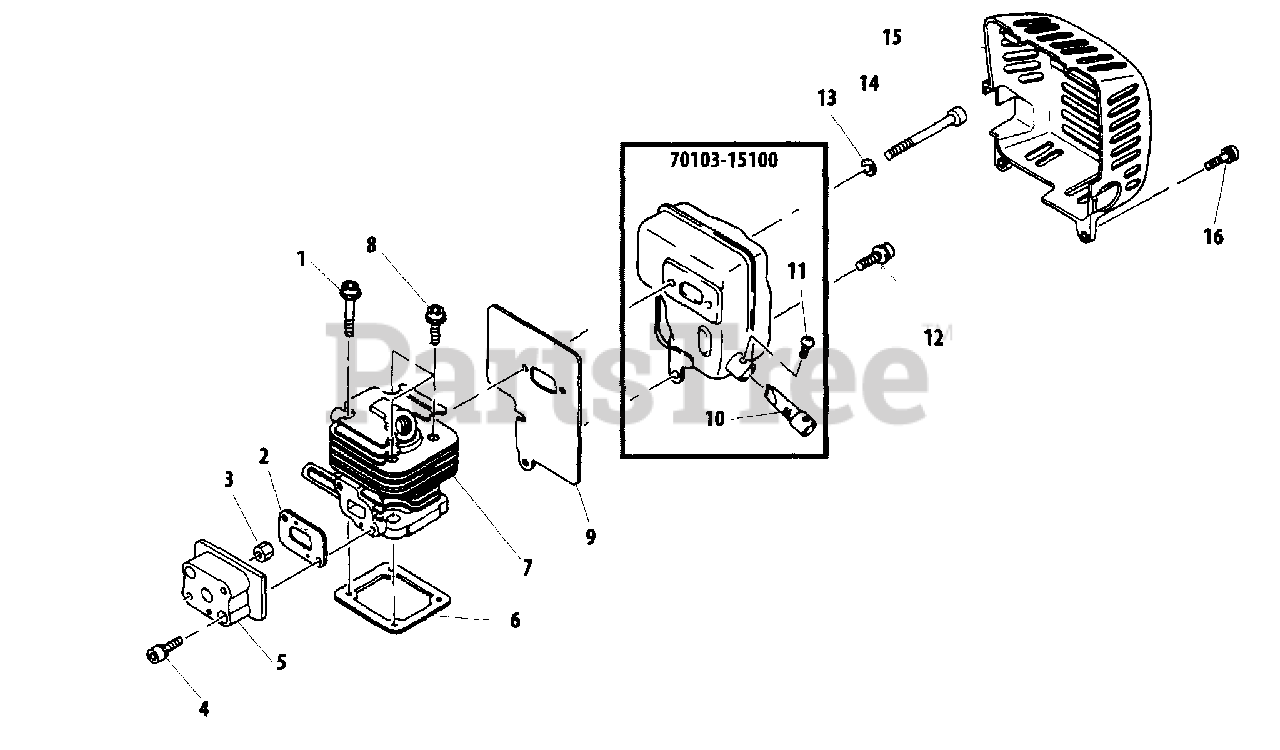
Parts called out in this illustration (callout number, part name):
1	SCREW - 5X30
2	GASKET, INTAKE
3	NUT
4	SCREW - 5X20
5	INSULATOR
6	GASKET, CYLINDER
7	CYLINDER
8	SCREW - 5X16
9	GASKET, EXHAUST
10	SCREEN, SPARK ARRESTOR
11	SCREW - 3X6
12	SCREW - 5X12
13	WASHER - 5
14	SCREW - 5X55
15	COVER, MUFFLER
16	SCREW - 5X16
70103-15100	MUFFLER ASSY
